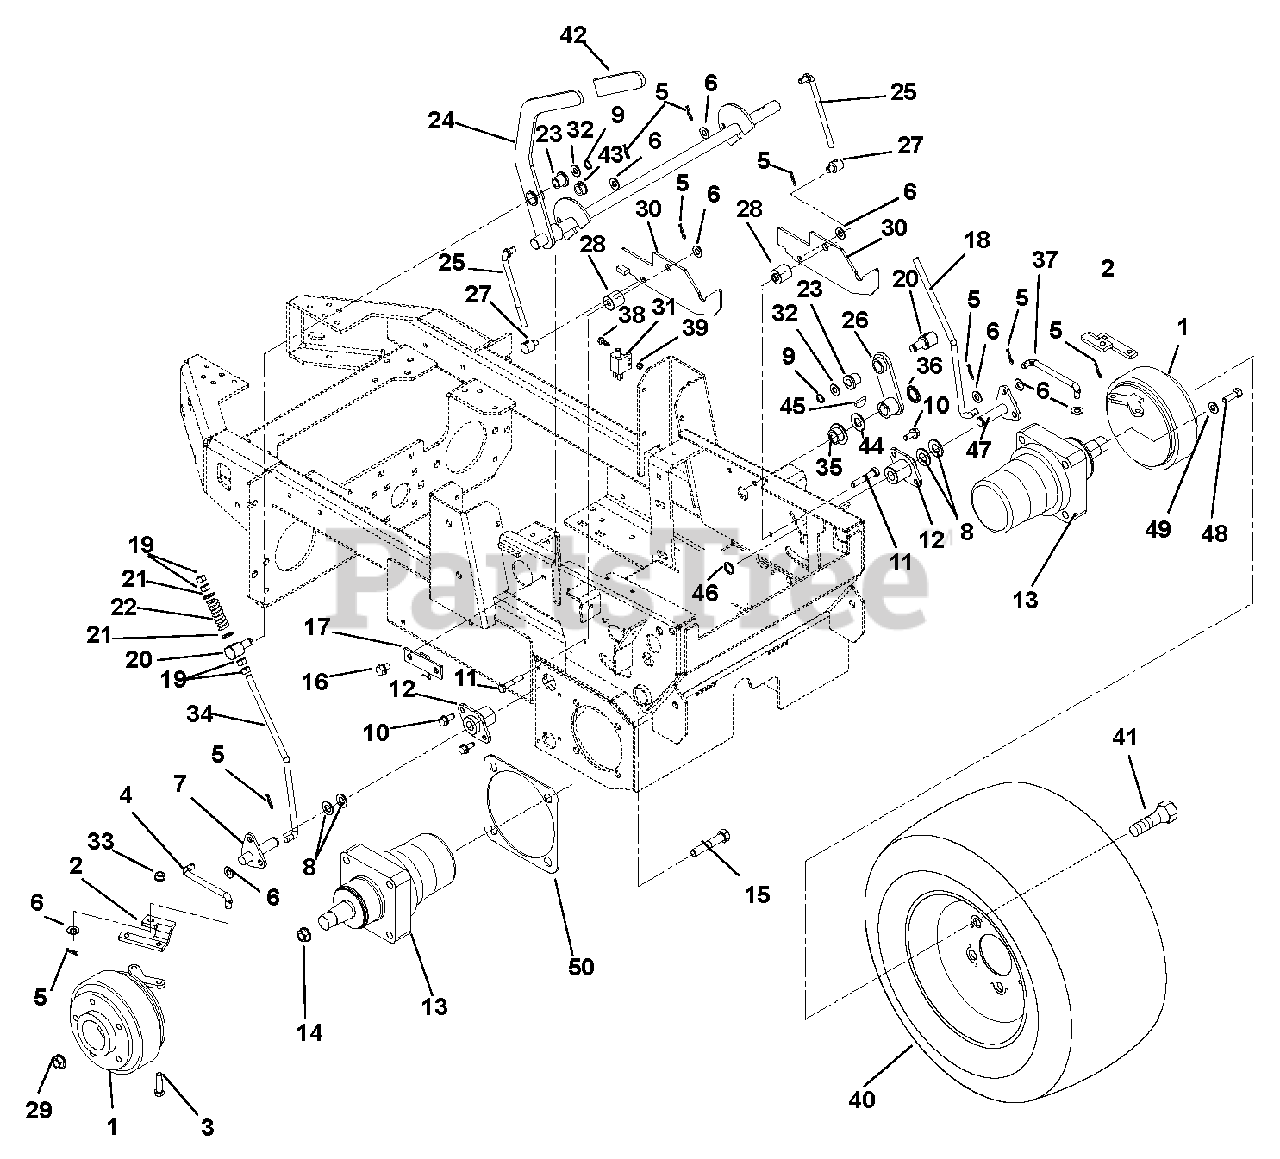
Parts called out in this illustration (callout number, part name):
1	ASSEMBLY, BRAKE
2	EXTENSION-BRAKE
3	@BLT-HEX .31-18X1.00 GR5 YWZC
4	ROD, PARKING BRAKE SET (RH)
5	PIN-HAIR, ENDRIES #25 YWZC
6	@WSHR-FL-STL.406X.812X.065 YWZ
7	WMT, PARKING BRAKE PIVOT, RH
8	WSHR-FL-STL .656X1.250X.10 YZC
9	RG-RTNG-EXT .500X.050 (SNAP)
10	@SCR-TAP .31-18X.75 HWH TR YWZ
11	@BLT-HEX .31-18X1.75 GR5 YWZC
12	BUSHING, FLANGED
13	MOTOR, PARKER TF0360LS080AAWN
14	NUT-LK-TOP-FLG .50-13 YWZC
15	BOLT, WHEEL MOTOR 1/2-13X2.75
16	@SCR-TAP .38-16X.50 HWH TR YWZ
17	WMT, PARKING BRAKE HOLD DOWN
18	ROD, O.C. LH BRAKE
19	@NUT-HEX .38-16 YWZC
20	TRUNNION, PIVOT .38
21	BUSHING-FLG .39X.53X.38X1.00
22	SPRING, COMPRESSION
23	BSHG-FLG.500X.750X.750X1.000BR
24	WMT, PARKING BRAKE
25	ROD, BRAKE LINK .375-24 UNF
26	WMT, BRAKE LEVER-LH
27	TRUNNION, .375-24 UNF
28	SPCR, FLG .32X.49X.192X1.00
29	NUT-JAM CTRLK .75-16 YWZC
30	LATCH, BRAKE LOCK
31	SWITCH- DOUBLE POLE N.O./N.O.
32	WSHR-HDND-STL-THR.515X.97X.062
33	@NUT-LK-NYL-FLG .31-18 YWZC
34	ROD, O.C. RH BRAKE
35	BSHG-FLG .762X1.0X.580X1.48 NY
36	NUT, PUSH -.75" SHAFT
37	ROD, PARKING BRAKE SET (LH)
38	SCR-MCH 10-24X.75 HWH YWZC
39	NUT-LK-NYL 10-24 W/INSRT YWZC
40	TIRE/WHL ASM,RH BAR24X12.00-12
41	BLT-LUG .50-20X1.38 YWZC
42	GRIP,HANDLE
43	BUSHING, SPLIT .75X.81X.20THK
44	WSHR-HDND-THRST .758X1.23X.031
45	KEY-WDRF .19X.75 HRD #9
46	RG-RTNG-EXT .625X.050
47	WMT, PARKING BRAKE PIVOT, LH
48	BLT-HEX .31-18X1.50 GR8YZ EP30
49	@WSHR-LK .31X.078 REG YWZC
50	SPACER,WHEEL MOTOR - BLK
